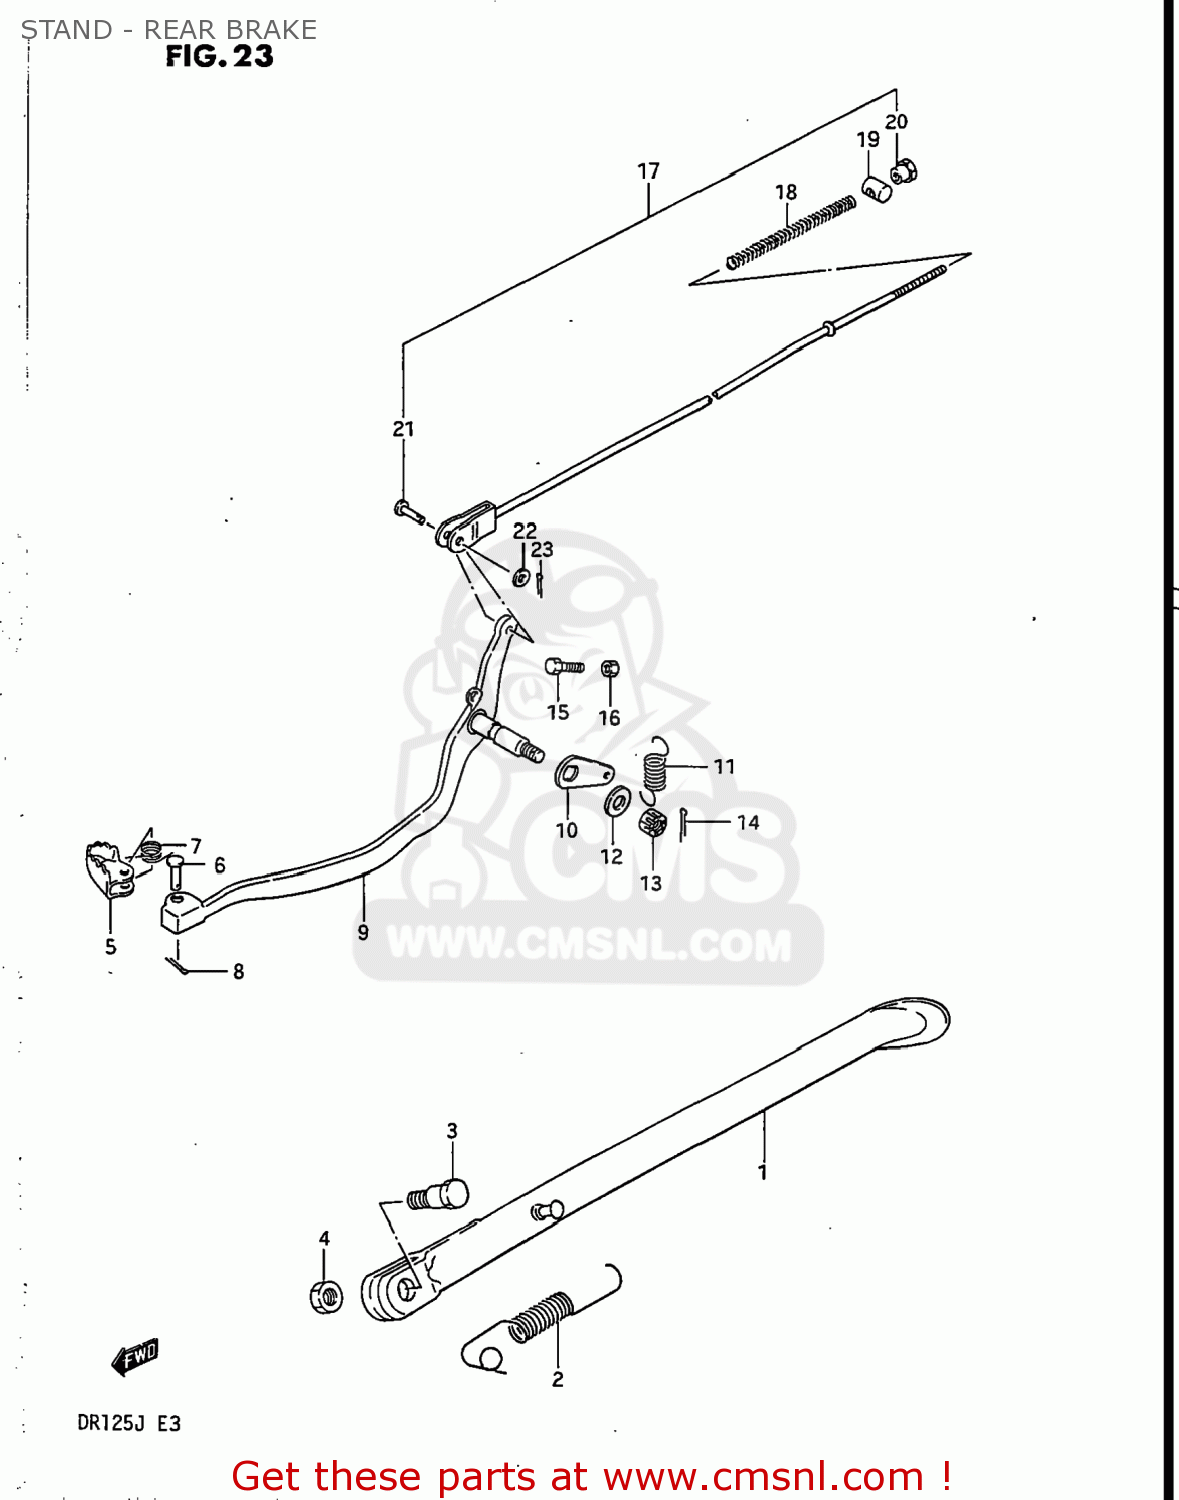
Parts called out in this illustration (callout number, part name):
1	STAND,SIDE
2	SPRING
3	BOLT L:30
4	NUT
5	PEDAL,BRAKE
6	PIN
7	SPRING
8	PIN
9	ARM,BRAKE PEDAL
10	ARM,BRAKE RETURN SPRING
11	SPRING
12	WASHER
13	NUT 8MM
14	PIN 20X20
15	BOLT(6X23)
16	NUT 6MM
17	ROD ASSEMBLY,REAR BRAKE
18	SPRING
19	PIN
20	NUT (6MM)
21	PIN(L:13.5)
22	WASHER
23	PIN 20X20
